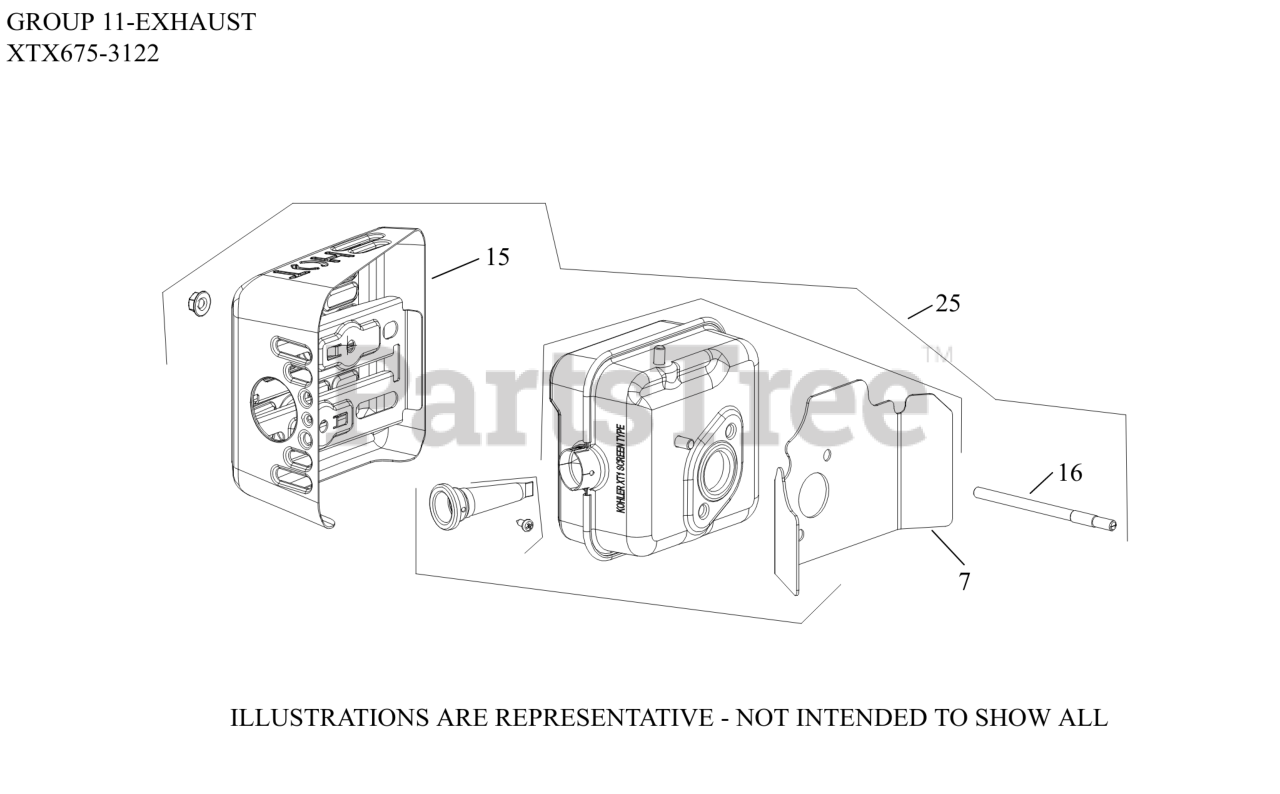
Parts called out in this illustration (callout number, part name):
7	GASKET, MUFFLER (HEAT DEFLECTOR)
15	GUARD, MUFFLER ASSEMBLY
16	STUD, EXHAUST (M6)
25	KIT, MUFFLER
